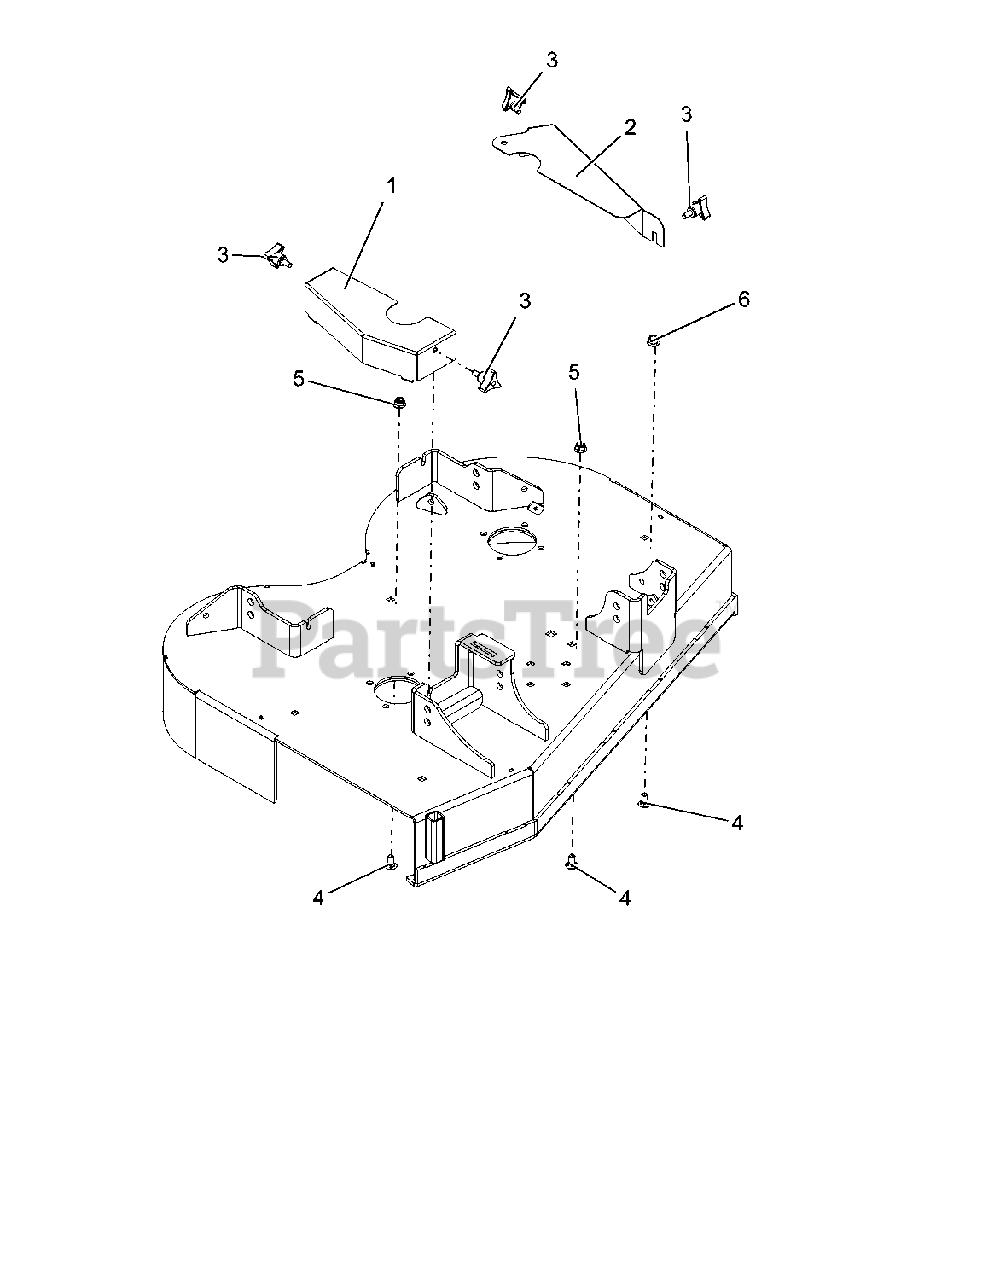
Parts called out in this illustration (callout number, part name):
1	GUARD, RH SPINDLE
2	GUARD, LH SPINDLE
3	KNOB,WING STUD 5/16-18 X .75
4	@BLT-RDHDSQNK .38-16X.75 G5YZ
5	@NUT-LK-NYL-FLG .38-16 YWZC
6	@NUT-LK-NYL-FLG .38-16 YWZC
